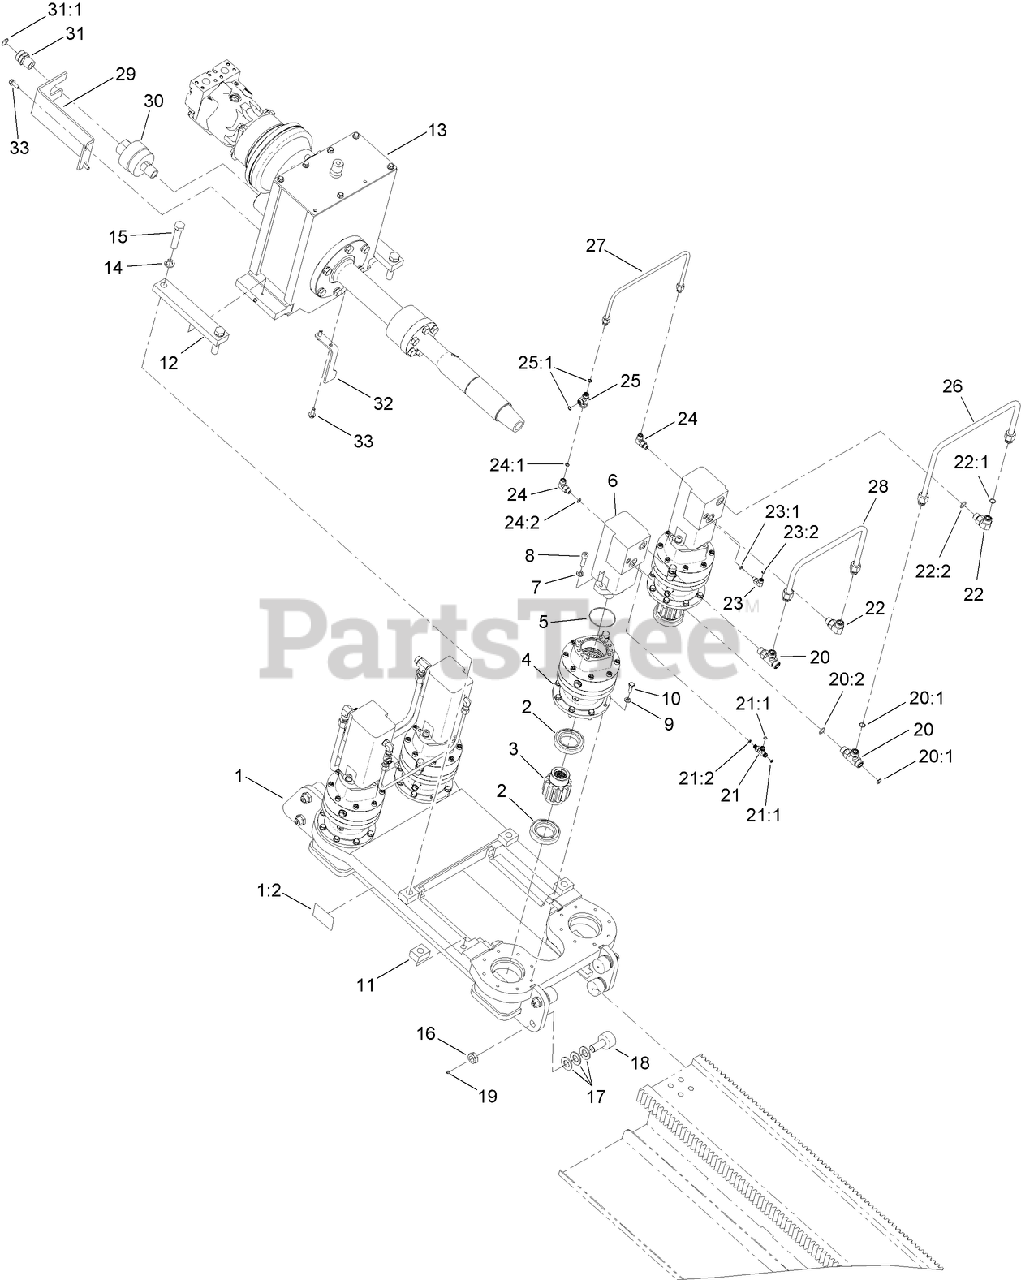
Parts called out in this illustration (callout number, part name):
1	CARRIAGE ASM
1:2	DECAL-DANGER, CRUSHING
2	BEARING-BALL, RADIAL
3	PINION-DRIVE, CARRIAGE
4	PLANETARY GEARBOX ASM
6	HYD MOTOR ASM
7	WASHER-LOCK
8	SCREW-HSH
9	WASHER-LOCK
10	SCREW-HH
11	SPACER-CLAMP, CARRIAGE
12	CLAMP-ROTARY BOX, CARRIAGE
13	ROTARY ASM
14	WASHER-LOCK
15	SCREW-HH
16	NUT-LOCK, NI
18	BEARING-FOLLOWER, CAM
19	FITTING-GREASE, ZERK
20	FITTING-TEE
20:1	O-RING
20:2	O-RING
21	FITTING-TEE
21:1	O-RING
21:2	O-RING
22	FITTING-ELBOW-90
22:1	O-RING
22:2	O-RING
23	FITTING-90 DEG
23:1	O-RING
23:2	O-RING
24	FITTING-ELBOW, 90 DEG
24:1	O-RING
24:2	O-RING
25	FITTING-TEE, SWIVEL NUT
25:1	O-RING
26	TUBE-HYD, 5/8 IN (MOTOR TO MOTOR)
27	TUBE-HYD, 3/8 IN (CASE DRAIN MOTOR TO MOTOR)
28	TUBE-HYD, 5/8 IN (MOTOR TO MOTOR)
29	BRACKET-SWIVEL, MUD
30	SWIVEL-MUD
31	FITTING-STRAIGHT
31:1	O-RING
32	PLATE-TRIGGER, PROXIMITY
33	SCREW-HHF
